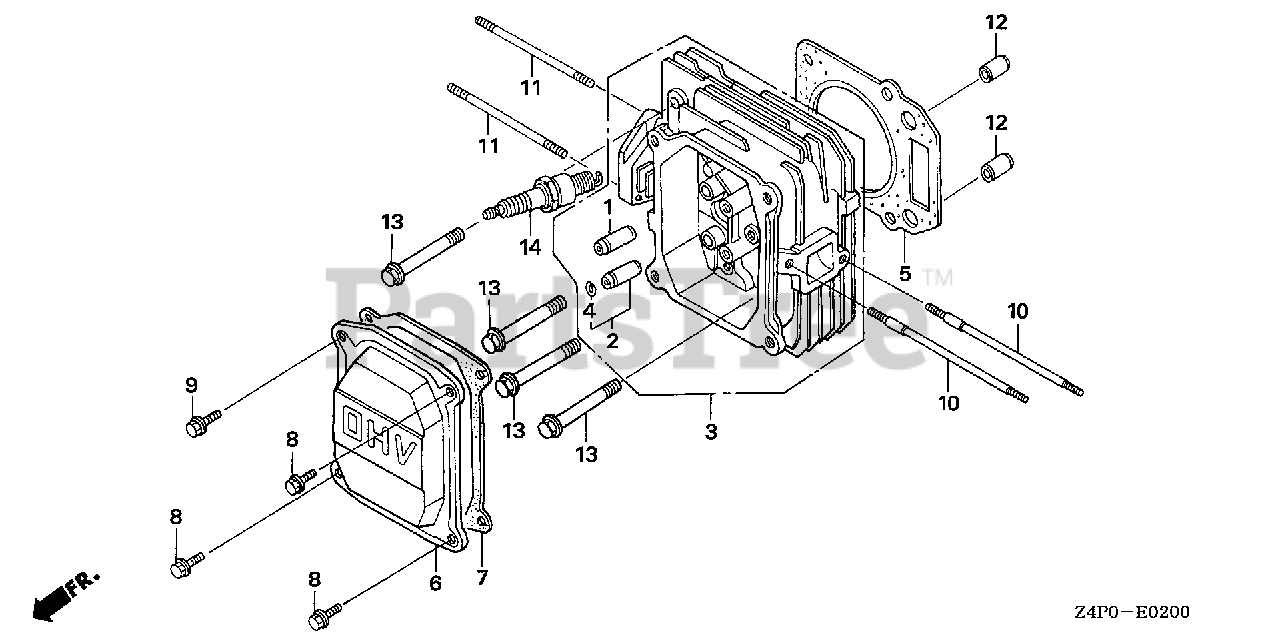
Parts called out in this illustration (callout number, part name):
1	GUIDE, VALVE (OVER SIZE)
2	GUIDE, EX. VALVE (OVER SIZE)
3	CYLINDER HEAD
4	CLIP, VALVE GUIDE
5	GASKET, CYLINDER HEAD (GUANGZHOU LEAKLESS)
6	COVER, HEAD
7	GASKET, HEAD COVER
8	BOLT, FLANGE (6X14) (CT200)
9	BOLT, FLANGE (6X14) (CT200)
10	BOLT, STUD (6X109)
11	BOLT, STUD (6X85)
12	PIN, DOWEL (10X16)
13	BOLT, FLANGE (8X50)
14	SPARK PLUG (BPR4ES) (NGK)
14	SPARK PLUG (W14EPR-U) (DENSO)
14	SPARK PLUG (BPR5ES) (NGK)
14	SPARK PLUG (W16EPR-U) (DENSO)
14	SPARK PLUG (BPR6ES) (NGK)
14	SPARK PLUG (W20EPR-U) (DENSO)
